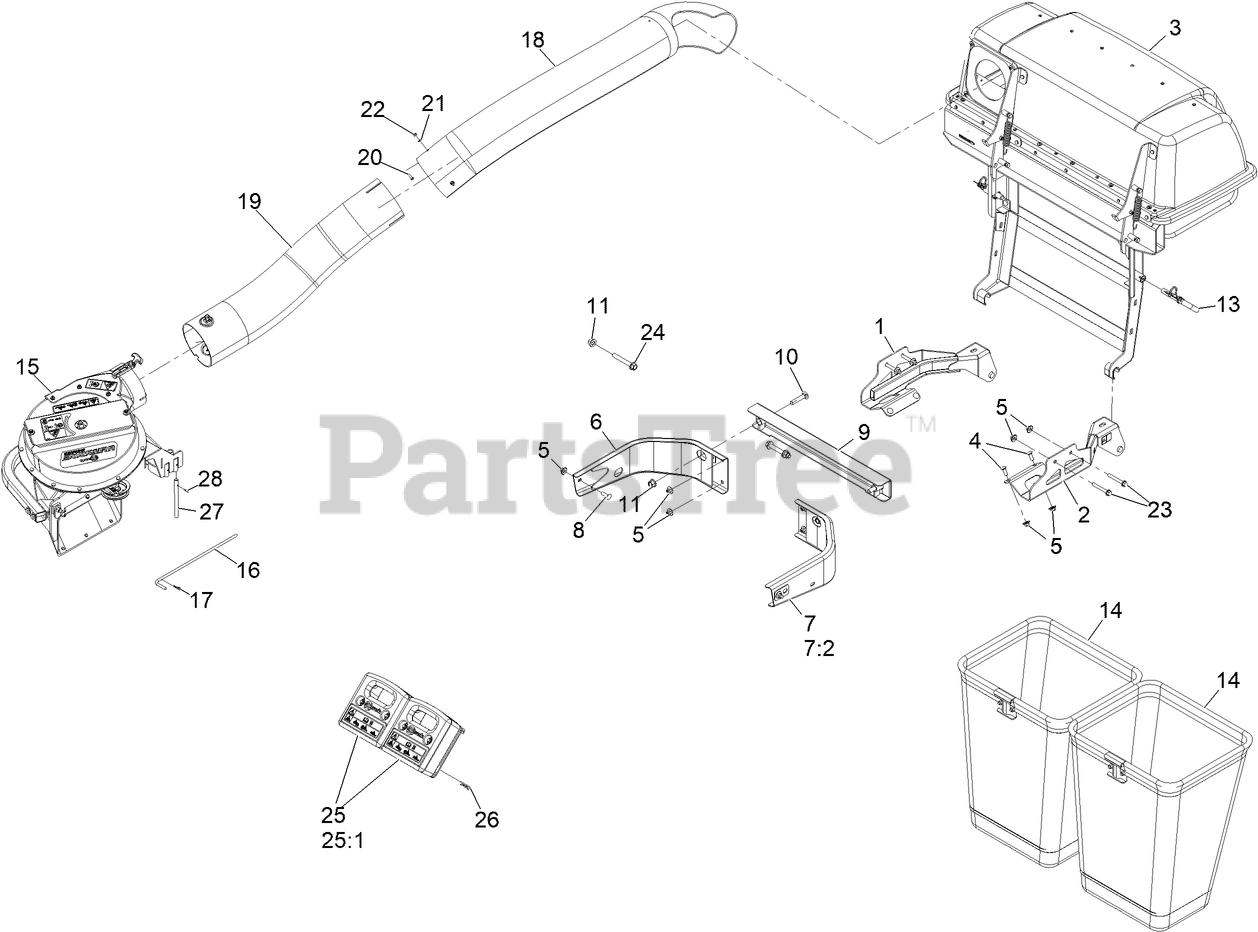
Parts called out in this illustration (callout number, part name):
1	ASM, BAGGER MOUNT W/ DECAL, RT
2	ASM, BAGGER MOUNT W/ DECAL, LT
3	Asm, Hood & Frame
4	SCREW-CARR
5	Nut-Nyloc 3/8-16 Flg
6	BUMPER-RH
7	LH BUMPER ASM
7:2	DECAL-WARNING
8	Bolt-Carriage 3/8-16 X 1 1/4
9	MOUNT-BAGGER, UPPER
10	SCREW-CARR
11	Nut-Lock 1/2-13
13	PIN-MOUNT, BAGGER
14	Bag And Frame ASM
15	ASM, UV BLOWER
16	PIN,CHUTE PIVOT
17	PIN-COTTER
18	TUBE-UPPER
19	ASM-TUBE, LOWER
20	SCREW-HWH
21	WASHER-FLAT
22	NUT-LOCK, NI
23	SCREW-HFH
24	SCREW-HHF
25	ASM,CAST WEIGHT
25:1	DECAL-WARNING WEIGHT
26	PIN-HAIR
27	SHAFT-CATCHER, GRASS
28	PIN-ROLL
